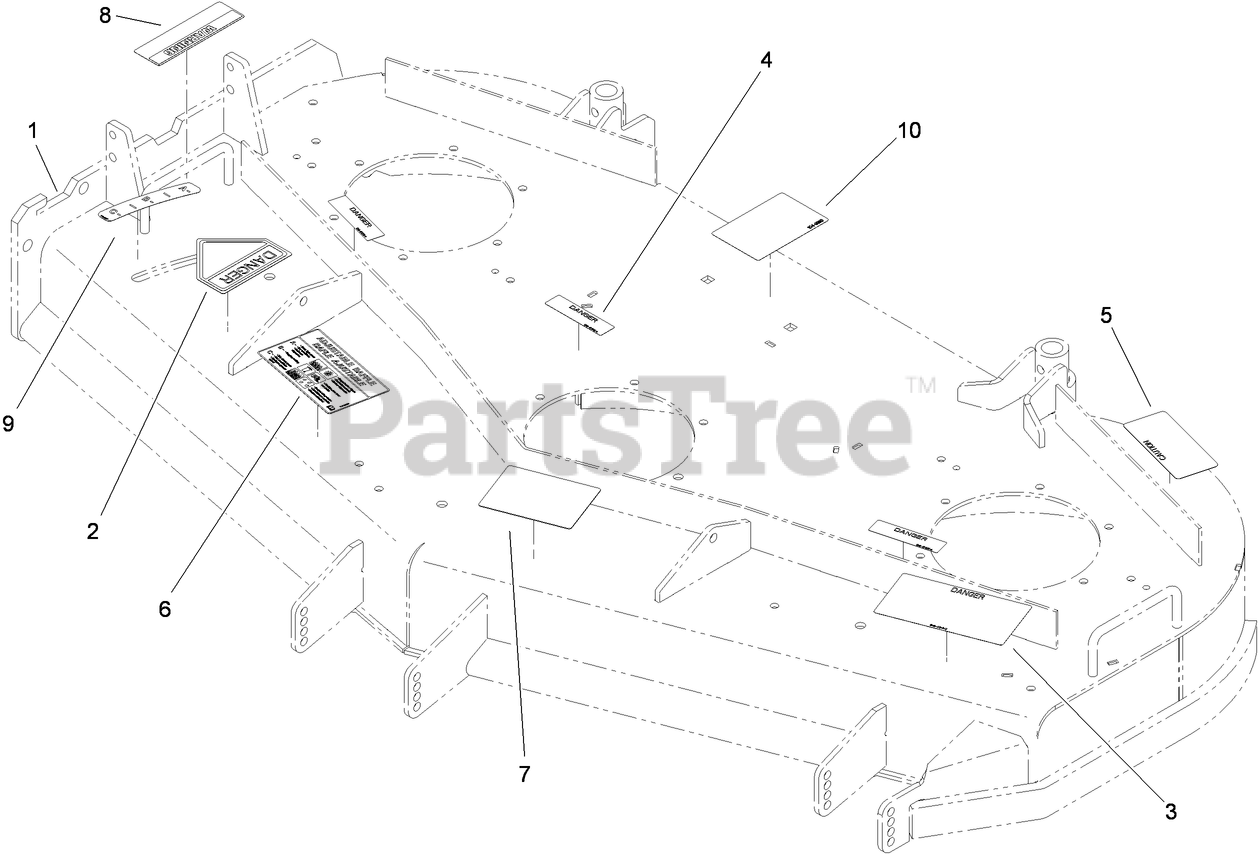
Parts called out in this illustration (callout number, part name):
1	52 INCH DECK ASM
2	DECAL-DANGER
3	DECAL-DANGER, THROWN OBJECT
4	DECAL-COVER, MISSING
5	DECAL-TORQUE
6	DECAL-ADJUSTMENT, BAFFLE
7	DECAL-SCALP, ANTI
8	DECAL-WARNING
9	DECAL-SETTING, BAFFLE
10	DECAL-ROUTING, BELT
